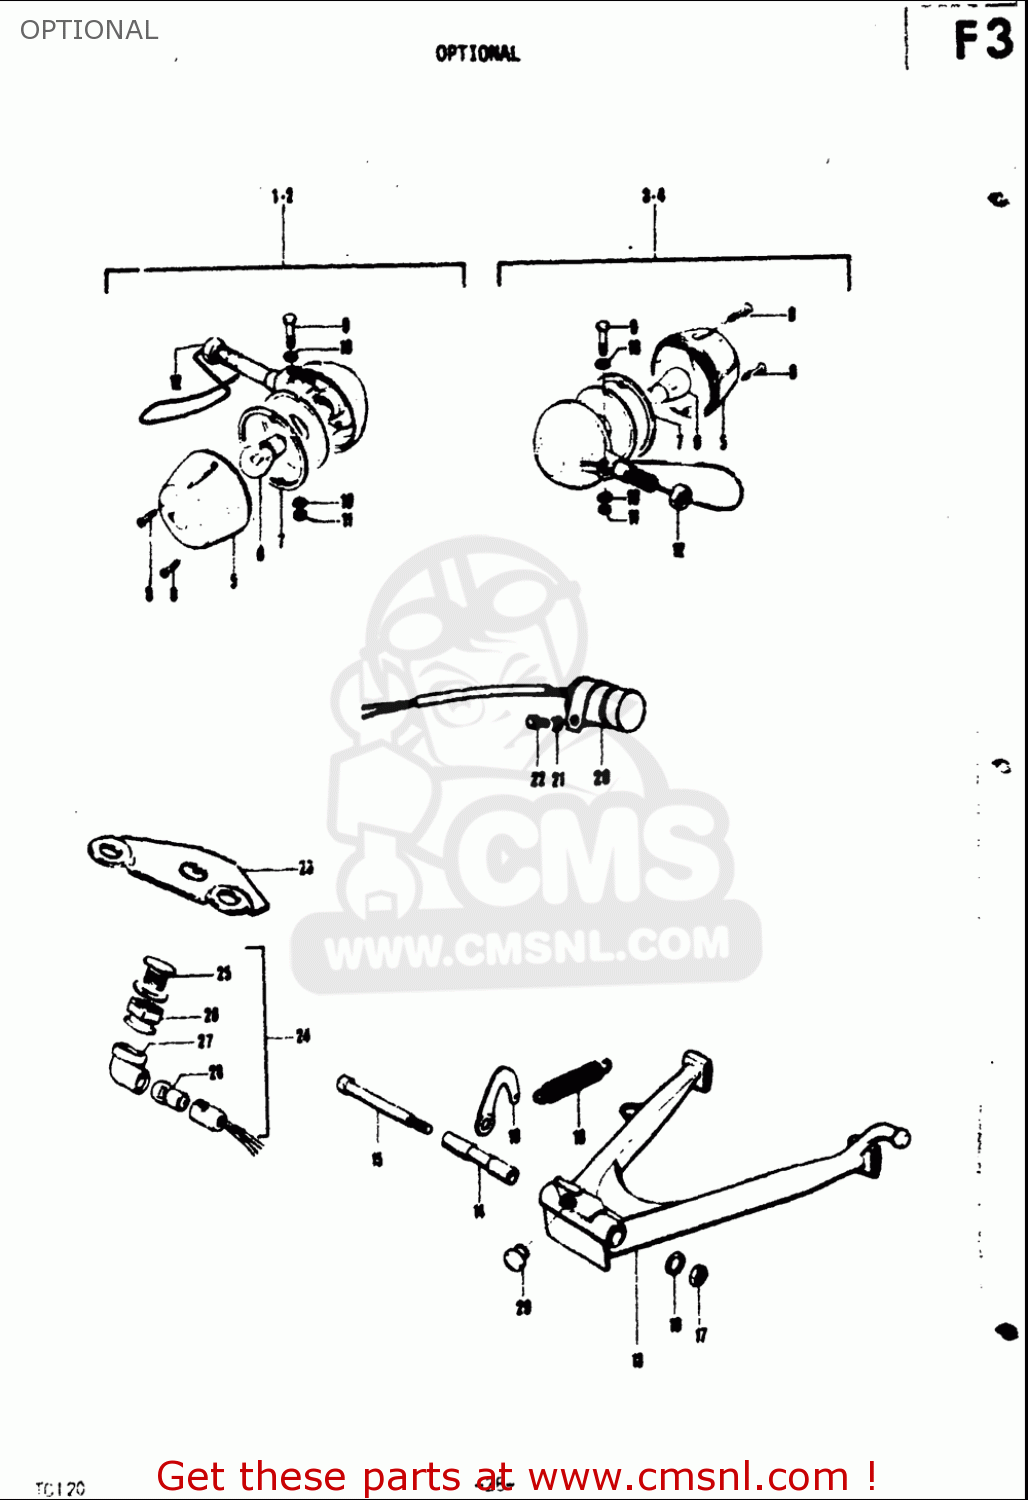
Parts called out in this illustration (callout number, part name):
5	LENS,TURNSIGNAL
6	BULB(6V17W,STANLEY,A4513A)
7	GASKET,TURNSIGNAL LENS (NAS)
10	WASHER
11	NUT
12	NUT
14	SPACER
15	BOLT
16	WASHER,LOCK
17	NUT
18	HOOK,CENTER STAND SPRING
19	SPRING
20	RELAY ASSY,TURNSIGNAL
21	WASHER,LOCK
28	BULB(6V1.7W,STANLEY,A61A)
29	CUSHION(11.5X22X20)
